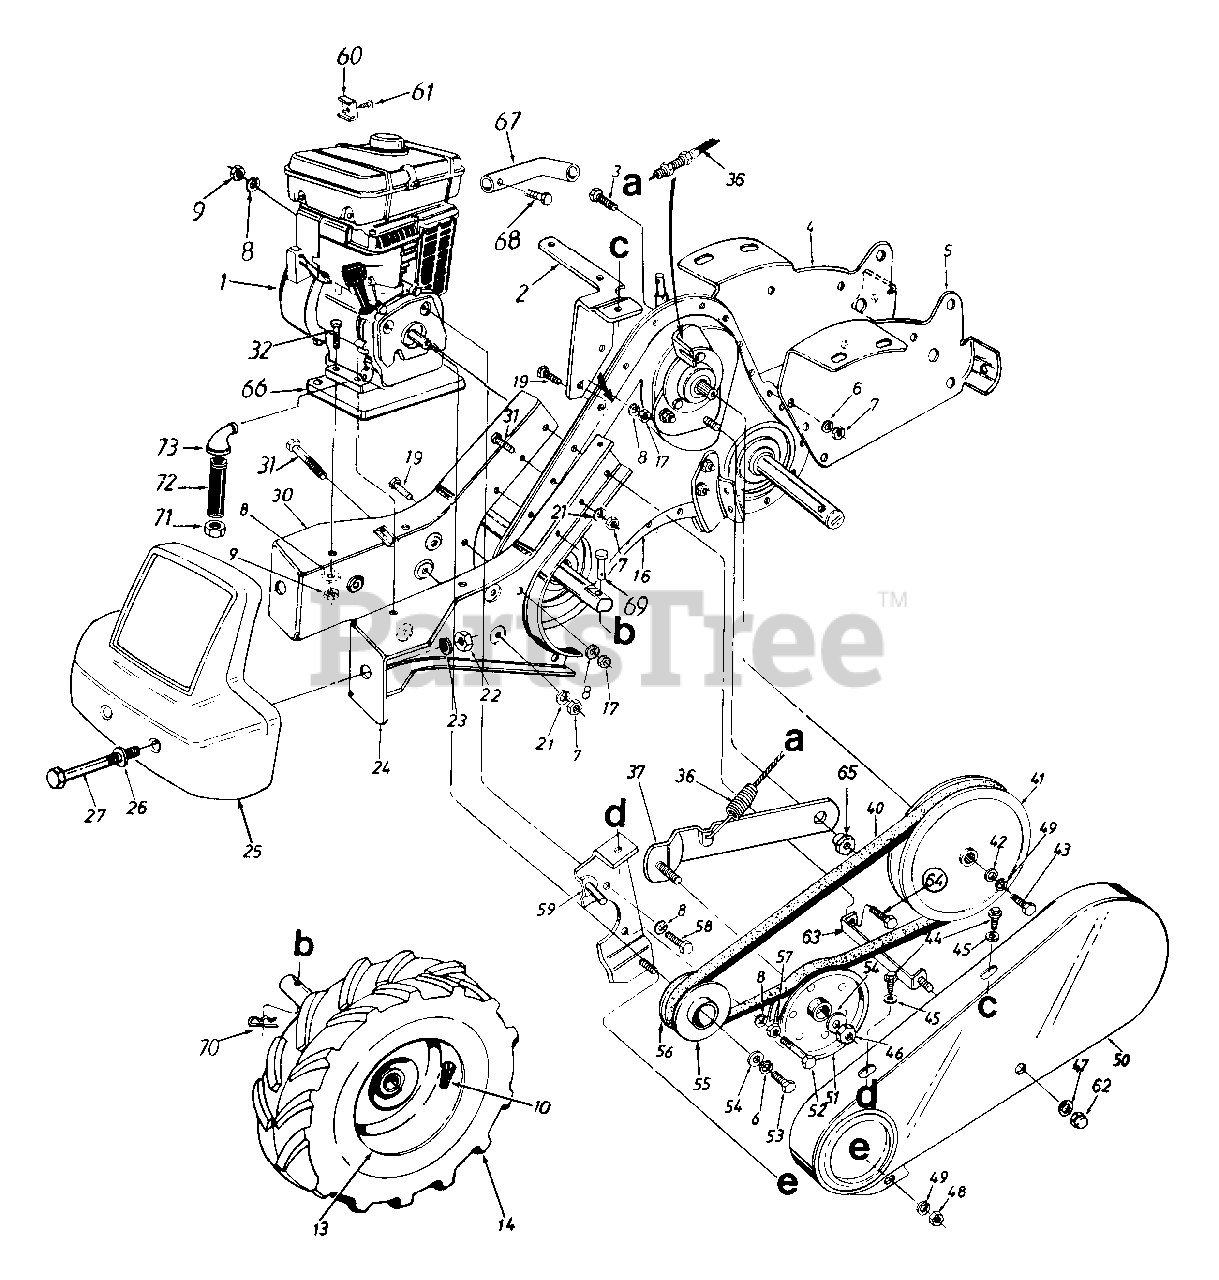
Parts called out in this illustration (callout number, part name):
1	Engine
7	Hex Nut 3/8-16 Thd.
8	L-Wash. 5/16" I.D.
9	Hex Nut 5/16-18" Thd.
10	Air Valve
16	Gear Case Ass'y. Comp.
17	Hex Nut 5/16-18 Thd.
19	Hex Bolt 5/16-18 x .75" Lg.
21	L-Wash. 3/8" I.D. - H.D.
22	Hex Nut 1/2-13 Thd.
23	L-Wash. 1/2" I.D.
26	Fl-Wash. .510" I.D. x 1.0"
27	Hex Bolt 1/2-13 x 5.00" Lg.
32	Hex Bolt 5/16-18 x 2.75"
36	Clutch Control Cable 46" Lg.
37	Idler Bracket Ass'y.
40	"V"-Belt
41	Fl-Pulley 8" O.D.
42	Fl-Wash. 1/4" I.D. x .93" O.D.
43	Hex Bolt 1/4-28 x .75" Lg.
44	Hex Wash. Hd. S-Tap Scr. 1/4-20 x .50" Lg.
45	Fl-Wash. .281" I.D. x .625"
46	Hex Cent. L-Nut 3/8-24 Thd.
47	Fl-Wash. .266" I.D. x .625" O.D.
48	Hex Nut 1/4-20 Thd.
49	L-Wash. 1/4" I.D.
51	Fl-Idler w/Flanges 3.75" O.D.
52	Hex Bolt 5/16-24 x 1.75"
53	Hex Bolt 3/8-24 x 1.00" Lg.
54	Fl-Wash. 3/8" I.D. x 1.00"
55	Outer Engine Pulley Half
56	Inner Engine Pulley Half
57	Hex Nut 5/16-24 Thd.
58	Hex Bolt 5/16-24 x .62" Lg.
59	Belt Keeper Ass'y.
60	Casing Clamp
61	Hex Sems Scr. #10-32 x .62"
62	Hex Cap Nut 1/4-28 Thd.
63	Belt Cover Brkt. Ass'y.
64	Hex Bolt 5/16-18 x 1" Lg. (Gr. 5)
65	Shld. Nut
66	Engine Spacer Block
67	Outlet Pipe
68	Hex Wash. Hd. AB-Tap Scr. #8 x .5" Lg.
69	Clevis Pin
70	Hairpin Clip
71	Oil Cap 1/4" NPT
72	Drain Pipe 1/4" NPT
73	Street Elbow 1/4" NPT
